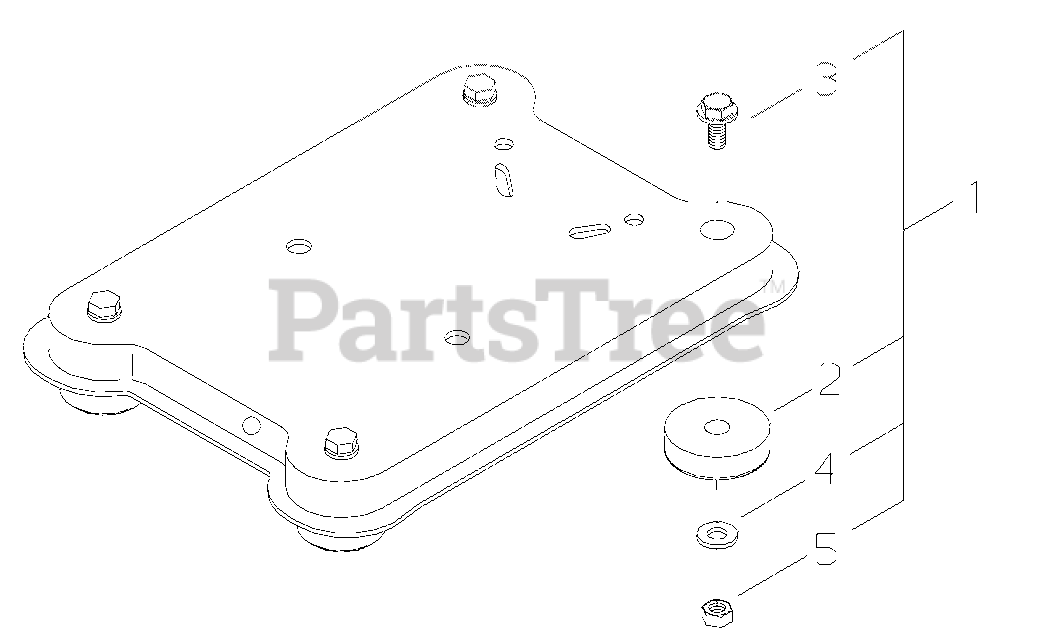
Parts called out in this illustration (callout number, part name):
1	BASE, PURGE
2	CUSHION
3	BOLT - 6X16
